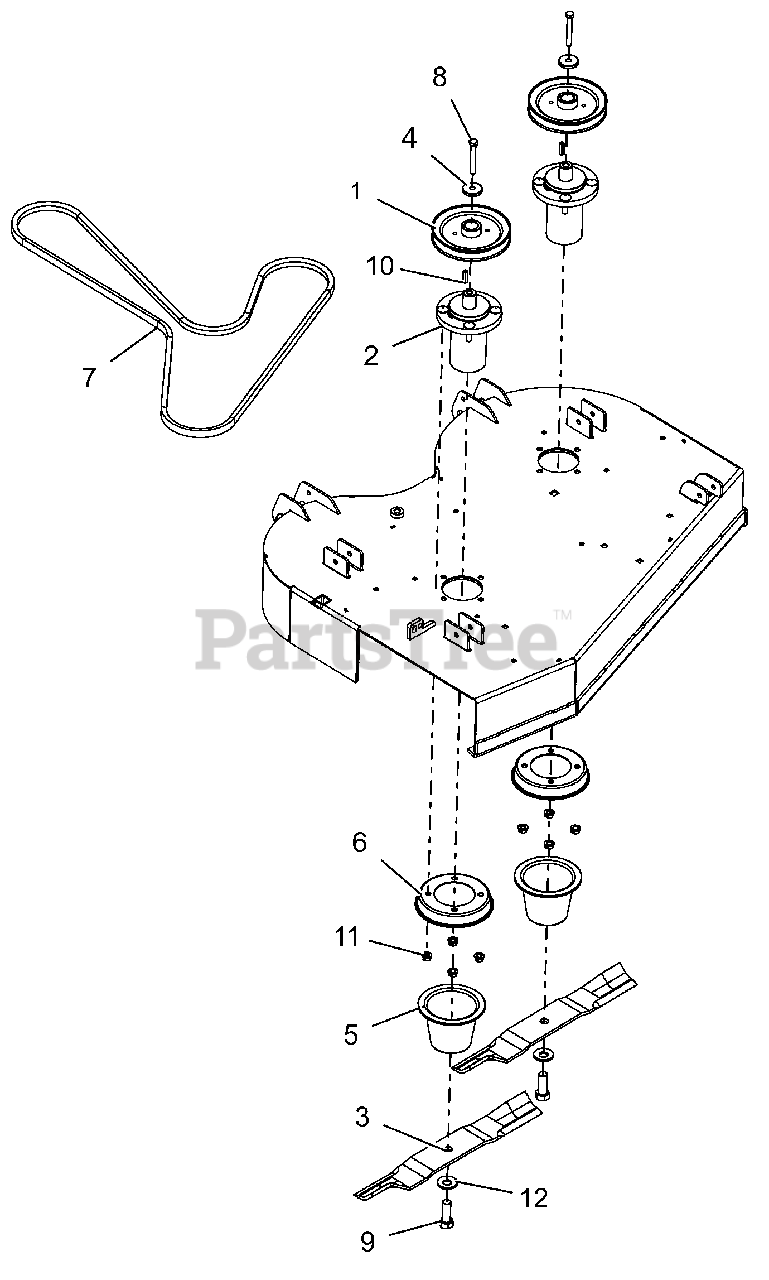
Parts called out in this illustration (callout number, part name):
1	PULLEY, V-1" ID X 6.00 OD
2	ASM, MAINT FREE ALUM SPINDLE
3	BLADE, 18.00" MOWER (HI-LIFT)
4	RETAINER, SHEAVE
5	GUARD, SPINDLE LOWER
6	GUARD, SPINDLE TOP
7	V-BELT, B RAW EDGE EPDM
8	BLT-HEX .38-16X2.75 GR8 YWZC
9	BLT-HEX .62-18X1.75 GR8 YWZC
10	KEY, SQ .25X.25X1.00 RC 40-50
11	NUT-LK-CTR-FLG .38-16 YWZC
12	WSHR-BLVL .669X1.535X.138
